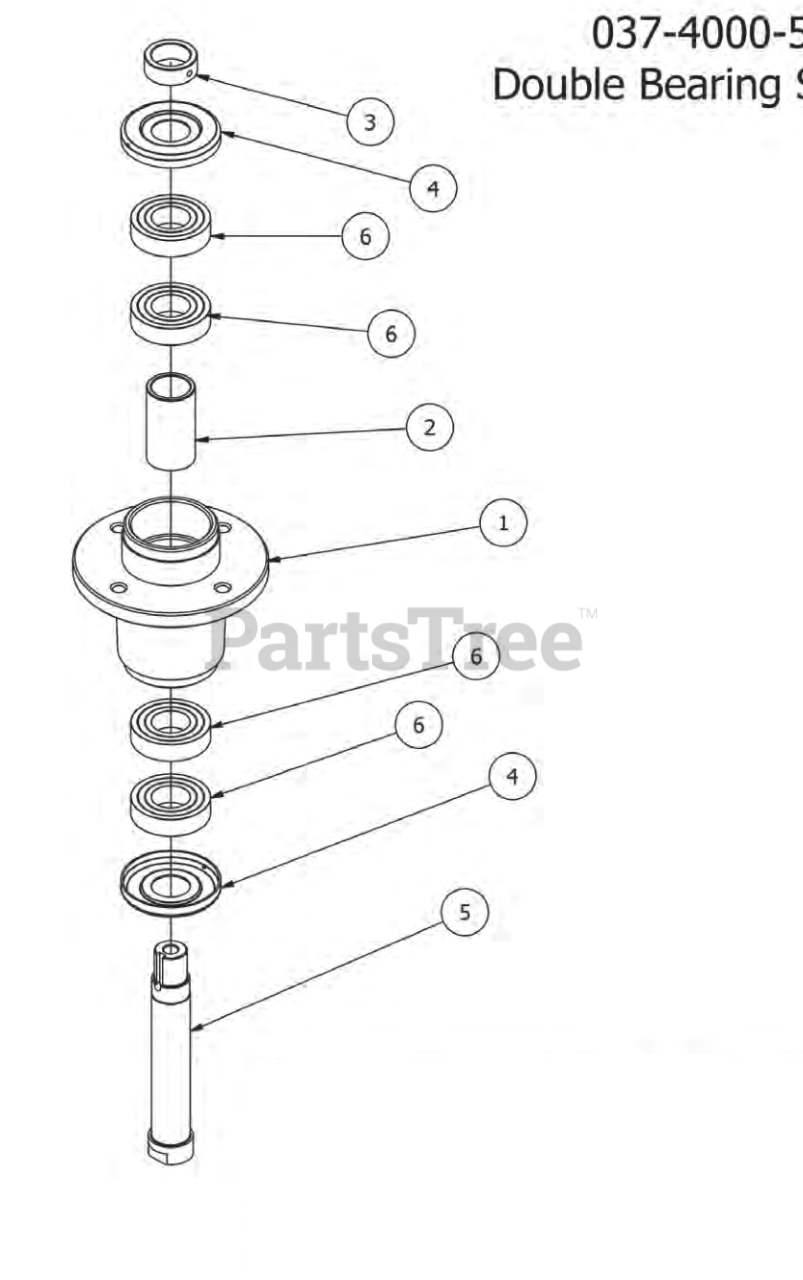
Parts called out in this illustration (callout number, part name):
1	4000 Series Spindle Housing
2	4000 Series Spindle Spacer
3	Locking Collar w/ 1/4"-20 Set Screw
4	Spindle Dust Cap
5	ZT-AOS Spindle Shaft
6	Bearing-6206
